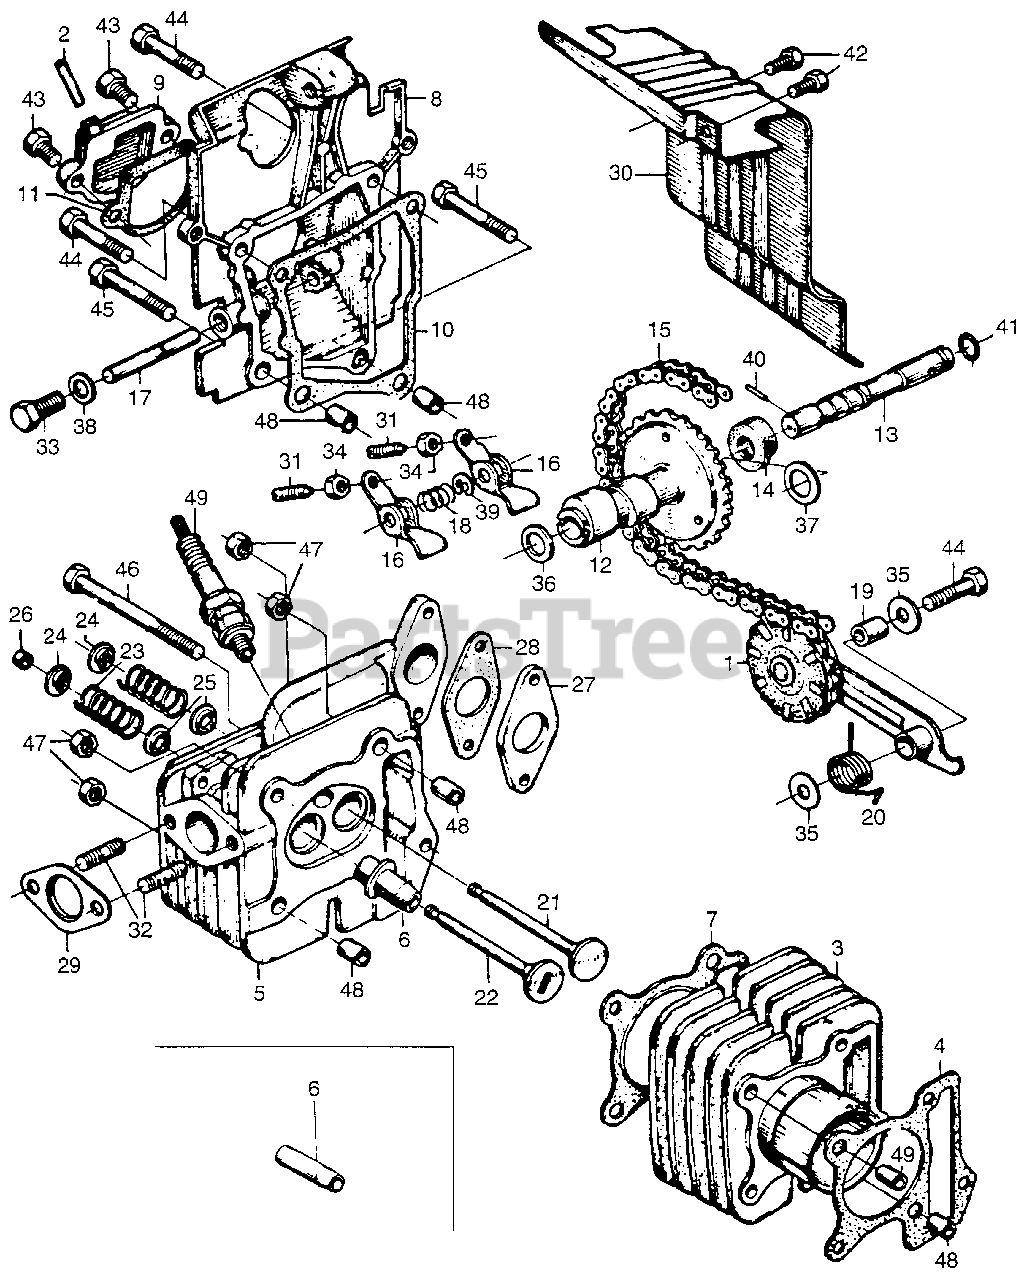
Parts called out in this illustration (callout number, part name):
1	TENSIONER, CAM CHAIN (NOT AVAILABLE)
2	JOINT, BREATHER (NOT AVAILABLE)
4	GASKET, CYLINDER (NOT AVAILABLE)
5	CYLINDER HEAD
6	GUIDE, VALVE (NOT AVAILABLE)
7	GASKET, CYLINDER HEAD
8	COVER, CYLINDER HEAD
9	CAP, TAPPET (NOT AVAILABLE)
10	GASKET, CYLINDER HEAD COVER
11	GASKET, CAP (NOT AVAILABLE)
13	PIN, CAMSHAFT CENTER (NOT AVAILABLE)
14	COLLAR, CAMSHAFT (NOT AVAILABLE)
15	CHAIN, CAM
16	ARM, VALVE ROCKER (NOT AVAILABLE)
17	SHAFT, VALVE ROCKER ARM (NOT AVAILABLE)
18	SPRING, ROCKER ARM SIDE (NOT AVAILABLE)
19	COLLAR, TENSIONER
20	SPRING, CAM CHAIN TENSIONER (NOT AVAILABLE)
21	VALVE, IN. (NOT AVAILABLE)
21	VALVE, IN.
22	VALVE, EX.
23	SPRING, VALVE (NOT AVAILABLE)
24	RETAINER, VALVE SPRING
25	SEAT, VALVE SPRING (LOWER) (NOT AVAILABLE)
26	ADJUSTER, TAPPET CLEARANCE (NOT AVAILABLE)
27	INSULATOR, CARBURETOR (NOT AVAILABLE)
28	GASKET, CARBURETOR INSULATOR
29	GASKET, EX. PIPE (NOT AVAILABLE)
30	VANE, GUIDE
31	SCREW, TAPPET ADJ. (NOT AVAILABLE)
32	BOLT STUD (6X23) (NOT AVAILABLE)
33	BOLT, SEALING (8MM) (NOT AVAILABLE)
34	NUT, TAPPET ADJ.
35	WASHER, SHIFT DRUM SIDE (NOT AVAILABLE)
36	WASHER A (10MM) (NOT AVAILABLE)
37	WASHER B (10MM) (NOT AVAILABLE)
38	GASKET, OIL PIPE JOINT
39	CIRCLIP (6MM)
40	PIN, KNOCK (3X12)
41	O-RING (6.9X1.5)
42	BOLT, HEX. (5X8)
43	BOLT, HEX. (6X16)
44	BOLT, HEX. (6X25)
45	BOLT, HEX. (6X35)
46	BOLT, HEX. (6X71) (NOT AVAILABLE)
47	NUT, HEX. (6MM)
48	PIN A, DOWEL (8X14)
49	SPARK PLUG (C6HSA) (NGK)
